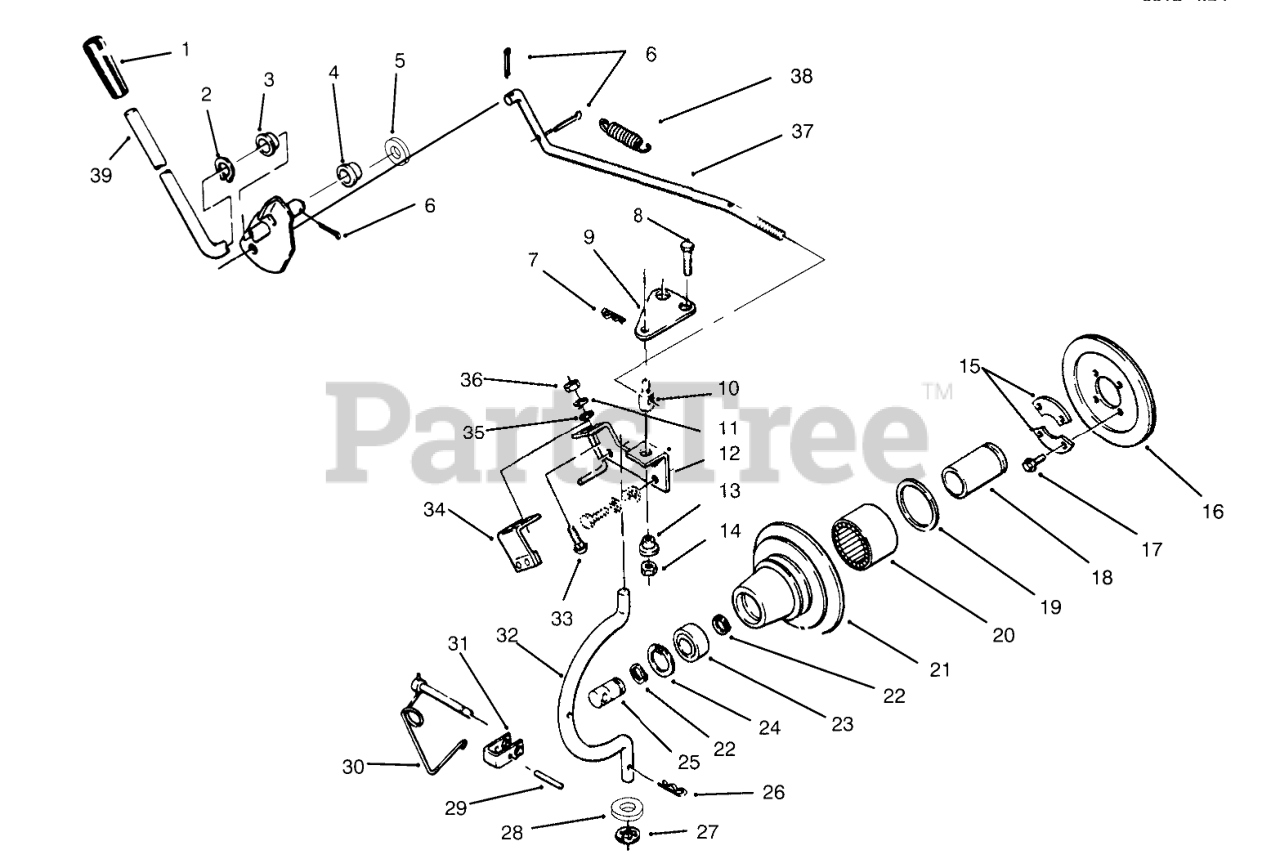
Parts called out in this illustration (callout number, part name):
1	GRIP
2	RING-EXT GRIP
3	BUSHING-NYLINER
4	NYLINER BUSHING
5	SHIM-WASHER
6	PIN-COTTER
7	PIN-HAIR
8	SCREW-HH
9	PLATE
10	TRUNNION
11	WASHER-LOCK
12	Bracket-Engine
13	SPACER-LIFT LINK
14	NUT-LOCK, NI
15	RETAINER
16	Facing-Clutch
17	SCREW-HEX HD CAP
18	RACE-BEARING
19	SEAL-OIL
20	Seal
21	Housing-Clutch
22	Ring-Snap
23	BEARING-BALL
24	RING-RETAINING
25	SHAFT-PTO
26	PIN-COTTER, HAIR
27	RING-REINFORCED CIRC
28	WASHER-FLAT
30	LOCKING PIN ASM
31	CLEVIS
32	ROD-HOUSING
33	SCREW-CARR
34	ASM-Bracket
35	WASHER-FLAT
36	NUT-JAM
37	ROD-PTO CLUTCH
38	SPRING
39	ASSY PTO CLUTCH LEVE
